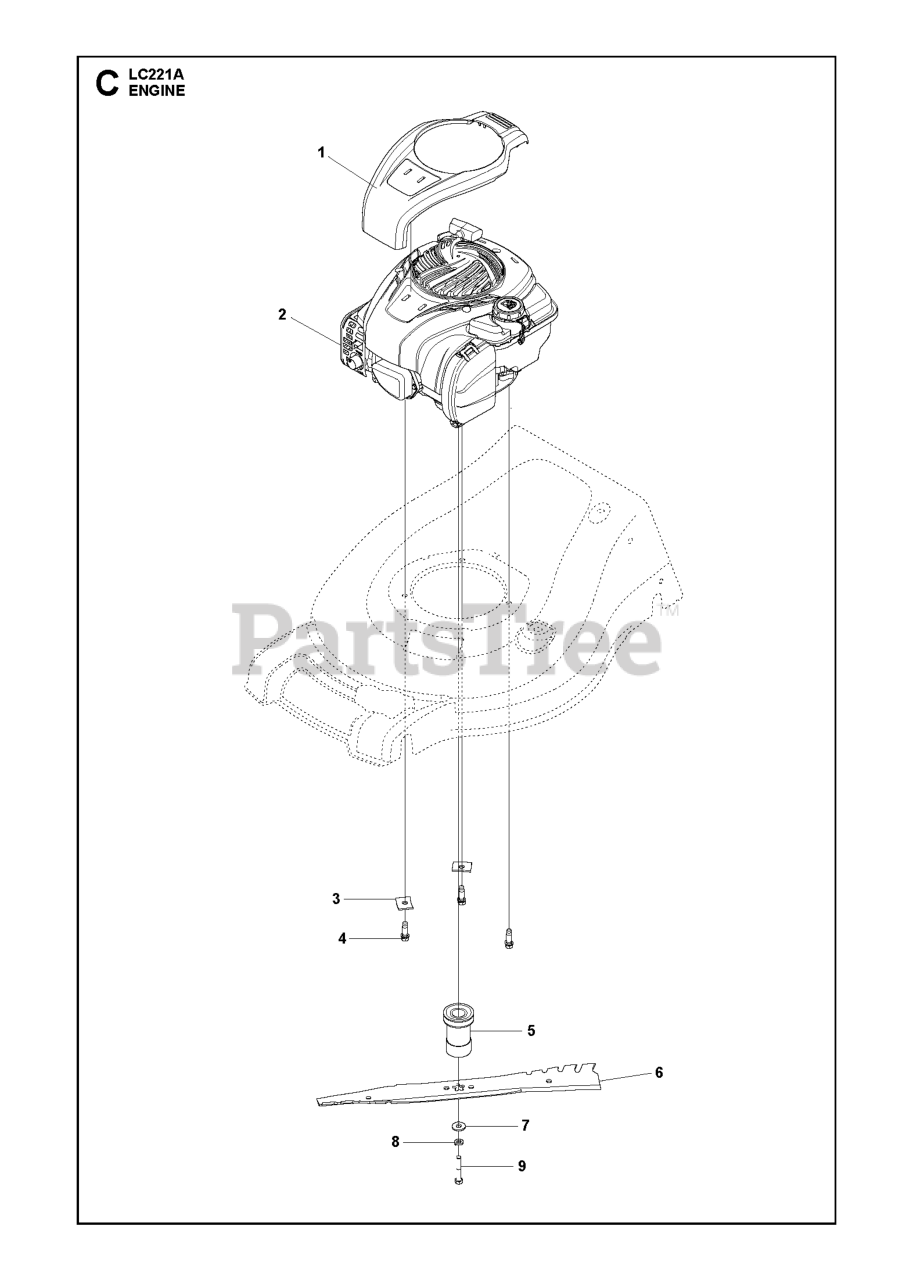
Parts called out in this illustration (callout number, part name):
3	WASHER.ENGINE.BZP
4	BOLT 3/8-16X1-1/8
5	ADAPTER.BLADE.7/8.5STR.EFF.AWD
6	BLADE.21.REAPER.WO/NOTCHES
7	WASHER,HARDEN
8	LOCKWASHER
9	BOLT.BLADE
